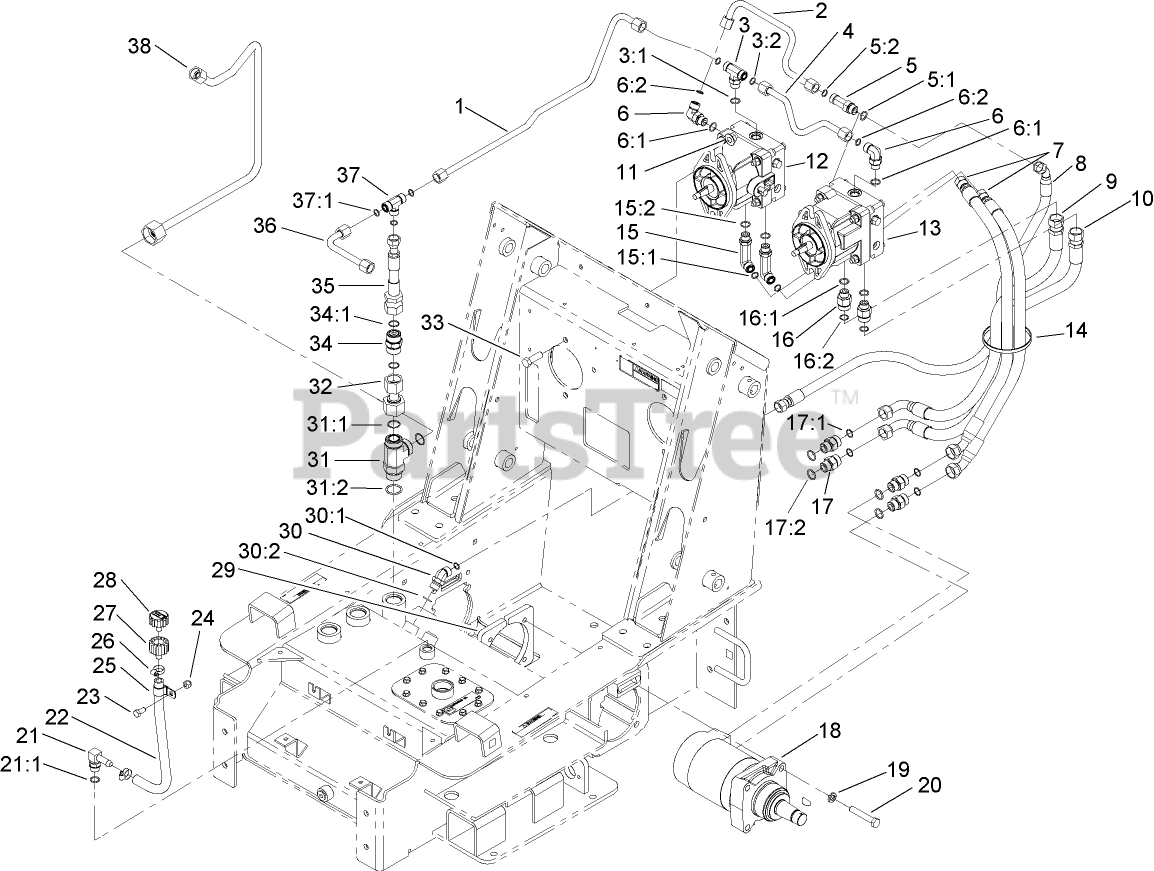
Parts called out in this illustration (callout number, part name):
1	HYDRAULIC TUBE ASM
2	TUBE-HYD
3	FITTING-HYD, TEE
3:1	O-RING
3:2	O-RING
4	TUBE-HYD
5	FITTING-TEE
5:1	O-RING
5:2	O-RING
6	FITTING-ELBOW-90 DEG
6:1	O-RING
6:2	O-RING
7	HOSE-HYD
8	HOSE-HYD
9	HYD HOSE ASM
10	HYD HOSE ASM
11	NUT-HF
12	RH HYD PUMP ASM
13	LH HYD PUMP ASM
14	TIE-CABLE
15	FITTING-ELBOW, 90 DEG
15:1	O-RING
15:2	O-RING
16	FITTING-STR
16:1	O-RING
16:2	O-RING
17	FITTING-STRAIGHT
17:1	O-RING
17:2	O-RING
18	HYD MOTOR ASM
19	WASHER-LOCK
20	SCREW-HH
21	FITTING-ELB 90
21:1	O-RING
22	HOSE-VENT
23	SCREW-HH
24	NUT-LOCK, NI
25	CLAMP-R
26	CLAMP-HOSE
27	ADAPTER-BREATHER
28	BREATHER
29	PLATE-MOUNTING
30	FITTING-HYD, 45 DEG
30:1	O-RING
30:2	O-RING
31	FITTING-TEE
31:1	O-RING
31:2	O-RING
32	TUBE-HYD
33	SCREW-HH
34	HYD CHECK VALVE ASM
34:1	O-RING
35	HYD HOSE ASM
36	HYD TUBE ASM
37	ADAPTER
37:1	O-RING
38	HYD TUBE ASM
